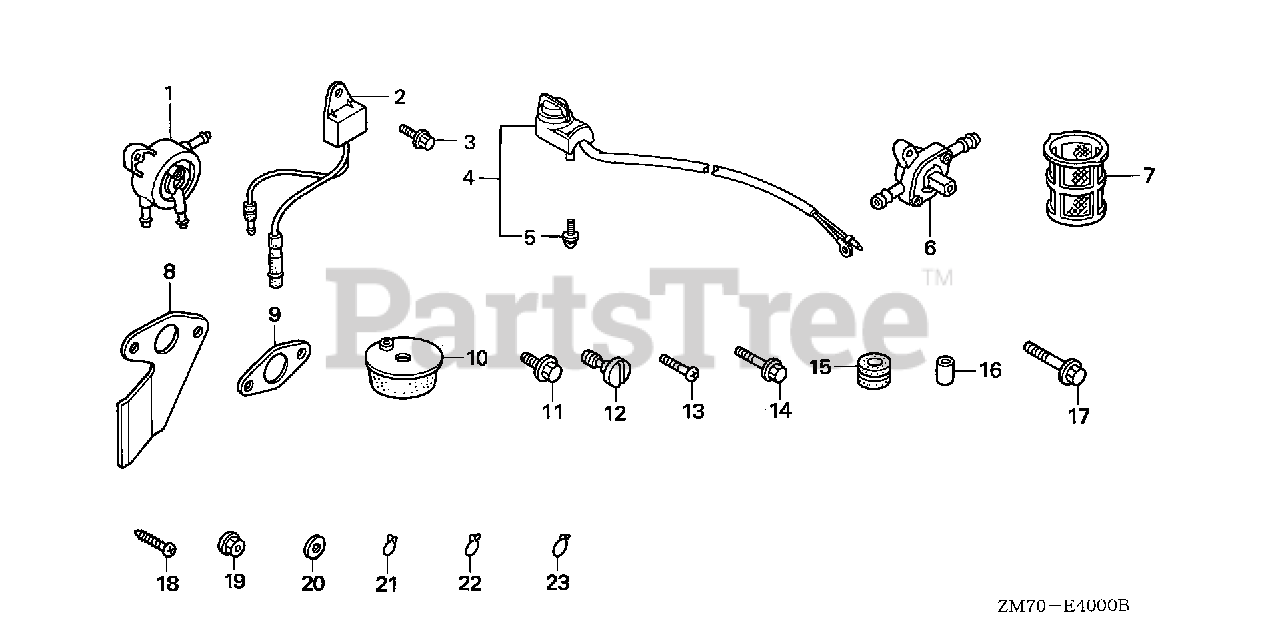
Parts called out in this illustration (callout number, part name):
1	PUMP ASSY., FUEL (MSDS)
2	ALERT UNIT, OIL
3	BOLT, FLANGE (6X8)
